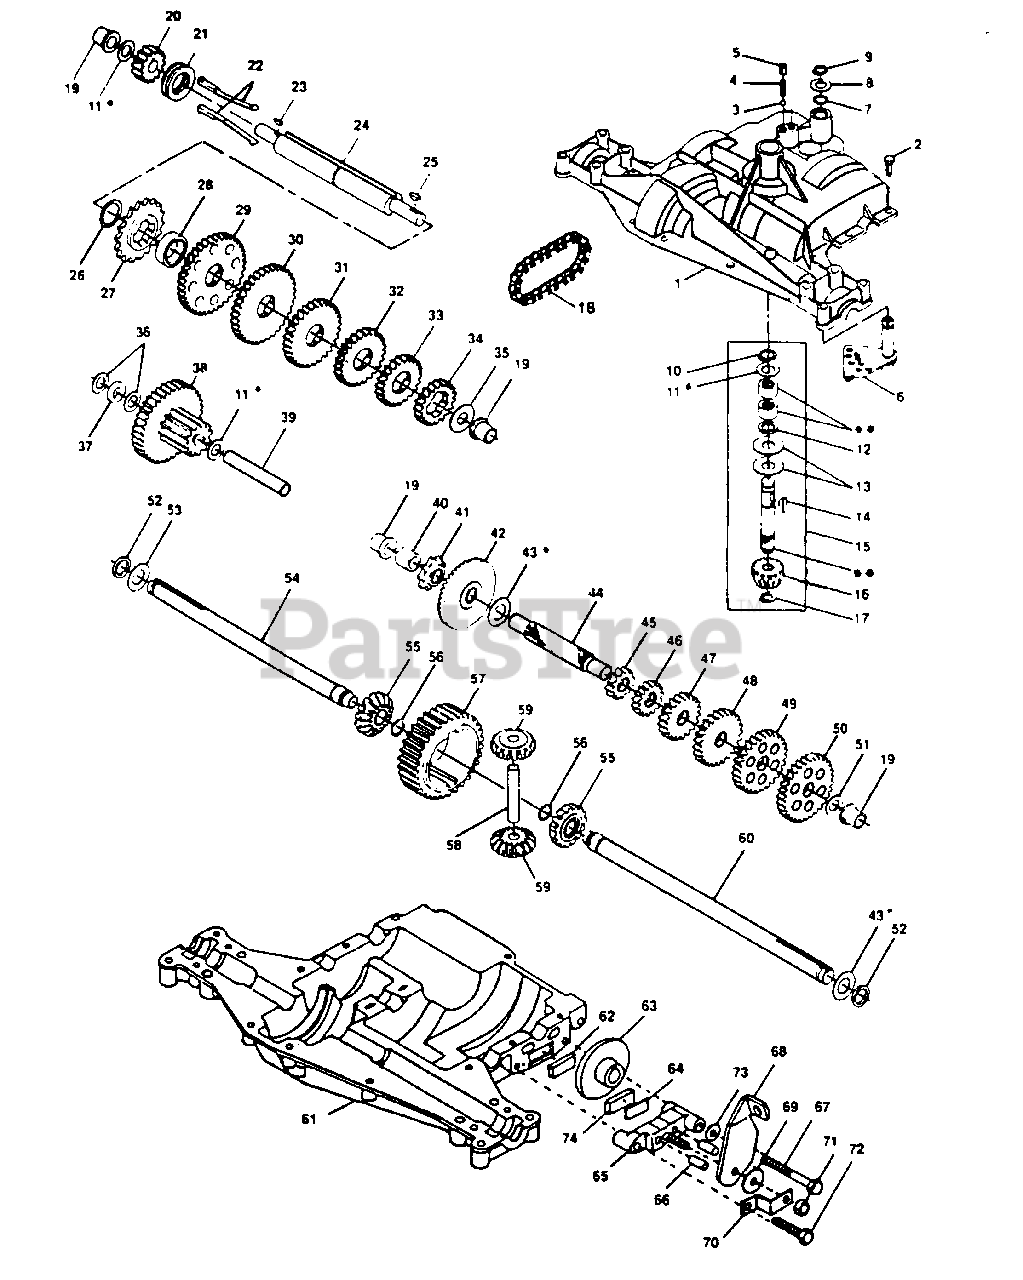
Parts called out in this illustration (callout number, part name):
1	Housing, Upper (Dana part number)
2	Screw, Tapping, 1/4-20 x .734 Lg. (Dana part number)
3	Ball, Detent (Dana part number)
4	Spring, Detent (Dana part number)
5	Screw, Set (Dana part number)
6	Ass;y., Shifter (Dana part number)
7	O-Ring (Dana part number)
8	Washer, Plain .505 x .942 x .006 (Dana part number)
8	Washer, Plain, .505 x .942 x .010 (Dana part number)
8	Washer, Plain, .505 x .942 x .015 (Dana part number)
8	Washer, Plain, .505 x .942 x .020 (Dana part number)
8	Washer, Plain, .505 x .942 x .026 (Dana part number)
8	Washer, Plain, .505 x .942 x .030 (Dana part number)
8	Washer, Plain, .505 x .942 x .040 (Dana part number)
9	Ring, Retaining (Dana part number)
10	Ring, Retaining (Dana part number)
11	Washer, Plain, .632 x 1.00 x .010 (Dana part number)
11	Washer, Plain, .632 x 1.00 x .020 (Dana part number)
11	Plain Washer .632 x 1.00 x .026 (Dana part number)
11	Washer, Plain, .632 x 1.00 x .031 (Dana part number)
11	Washer, Plain, .632 x 1.00 x .036 (Dana part number)
11	Washer, Plain, .632 x 1.00 x .041 (Dana part number)
11	Washer, Plain, .632 x 1.00 x .046 (Dana part number)
11	Washer, Plain, .632 x 1.00 x .050 (Dana part number)
11	Washer, Plain, .632 x 1.00 x .060 (Dana part number)
12	O-Ring (Dana part number)
13	Washer, Plain, .632 x 1.38 x .046
14	Key, Woodruff, #9
15	Ass'y., Kit, Input Shaft (Dana part number)
16	Pinion, Bevel, 14T. (Dana part number)
17	Ring, Retaining (Dana part number)
18	Chain, 24 Pitches (Dana part number)
19	Bearing, Flange (Dana part number)
20	Gear, Spur, 14T.
21	Collar, Clutch (Dana part number)
22	Key, Clutch (Dana part number)
23	Key, Woodruff
24	Shaft, Intermediate (Dana part number)
25	Key, Woodruff, #61(Dana part number)
26	Ring, Retaining (Dana part number)
27	Sprocket, 18T.(Dana part number)
28	Spacer (Dana part number)
29	Gear, Spur, 37T.
30	Gear, Spur, 35T.
31	Gear, Spur, 30T. (Dana part number)
32	Gear, Spur, 25T.
33	Gear, Spur, 22T. (Dana part number)
34	Gear, Spur, 19T. (Dana part number)
35	Washer, Plain, .640 x 1.37 x .061 (Dana part number)
36	Plain Washer .632 x 1.00 x .026 (Dana part number)
37	Spacer, .630 x 1.00 x .169 (Dana part number)
38	Ass'y., Gear, Comb., 12T. & 35T. (Dana part number)
39	Shaft, Idler (Dana part number)
40	Spacer, .635 x.875 x .755 (Dana part number)
41	Sprocket, 9T. (Dana part number)
42	Gear, Bevel, 42T. (Dana part number)
43	Washer, Plain, .758 x 1.12 x .010 (Dana part number)
43	Washer, Plain, .758 x 1.12 x .015 (Dana part number)
43	Washer, Plain, .758 x 1.12 x .020 (Dana part number)
43	Washer, Plain, .758 x 1.12 x .025 (Dana part number)
43	Washer, Plain, .758 x 1.25 x .020 (Dana part number)
43	Washer, Plain, .758 x 1.25 x .025 (Dana part number)
43	Washer, Plain, .758 x 1.25 x .031 (Dana part number)
43	Washer, Plain, .758 x 1.25 x .035 (Dana part number)
43	Washer, Plain, .758 x 1.25 x .040(Dana part number)
43	Washer, Plain, .758 x 1.25 x .045 (Dana part number)
43	Washer, Plain, .758 x 1.25 x .050 (Dana part number)
43	Washer, Plain, .758 x 1.25 x .055 (Dana part number)
43	Washer, Plain, .758 x 1.25 x .062 (Dana part number)
44	Shaft, Drive (Dana part number)
45	Gear, Spur, 12T. (Dana part number)
46	Gear, Spur, 15T. (Dana part number)
47	Gear, Spur, 20T. (Dana part number)
48	Gear, Spur, 25T. (Dana part number)
49	Gear, Spur, 28T. (Dana part number)
50	Gear, Spur, 31T. (Dana part number)
51	Washer, Plain, .632 x 1.00 x .060 (Dana part number)
52	Seal, Felt (Dana part number)
53	Washer, Plain, .758 x 1.25 x .062 (Dana part number)
54	Axle, L.H. (Dana part number)
55	Gear, Miter, 15T.
56	Ring, Retaining (Dana part number)
57	Gear, Spur, 32T. (Dana part number)
58	Shaft, Cross (Dana part number)
59	Gear, Miter, 15T.
60	Axle, R.H. (Dana part number)
61	Housing, Lower (Dana part number)
62	Puck, Friction (Dana part number)
63	Disc, Brake (Dana part number)
64	Spacer (Dana part number)
65	Jaw, Brake (Dana part number)
66	Pin, Dowel (Dana part number)
67	Screw, Tapping, 5/16-18 x 2 25 Lg. (Dana part number)
68	Lever, Actuating
69	Washer, Plain, ..321 x 1.00 x .055
70	Bracket, Anti-Rotation (Dana part number)
71	Nut, Lock, 5/16-24 (Dana part number)
72	Screw, Tapping, 5/16-18 x 1.44 Lg. (Dana part number)
73	Washer, Plain, .343 x .81 x .059
74	Puck, Friction (Dana part number)
75	Grease (Dana part number)
